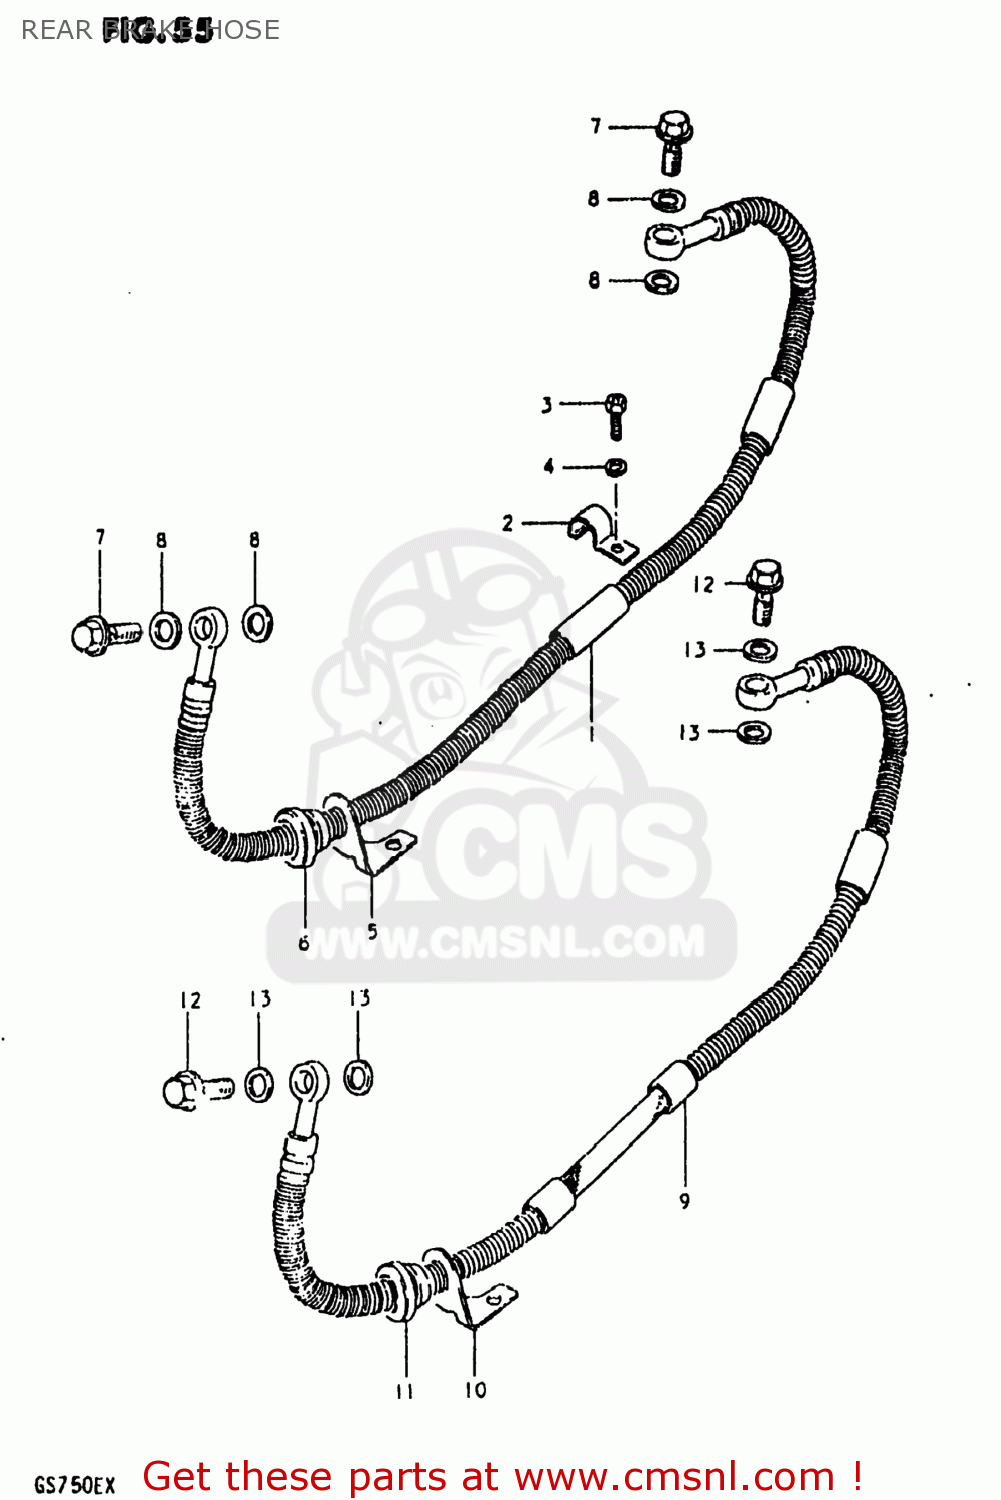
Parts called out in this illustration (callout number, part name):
1	HOSE,REAR BRAKE
2	CLAMP,REAR BRAKE HOSE
3	SCREW(6X8)
4	LOCK WASHER
5	GUIDE,BRAKE HOSE
6	GROMMET,BRAKE HOSE GUIDE
7	BOLT,UNION
8	WASHER
9	HOSE,REAR BRAKE
10	GUIDE,BRAKE HOSE
11	GROMMET,BRAKE HOSE GUIDE
12	BOLT,UNION
13	WASHER
